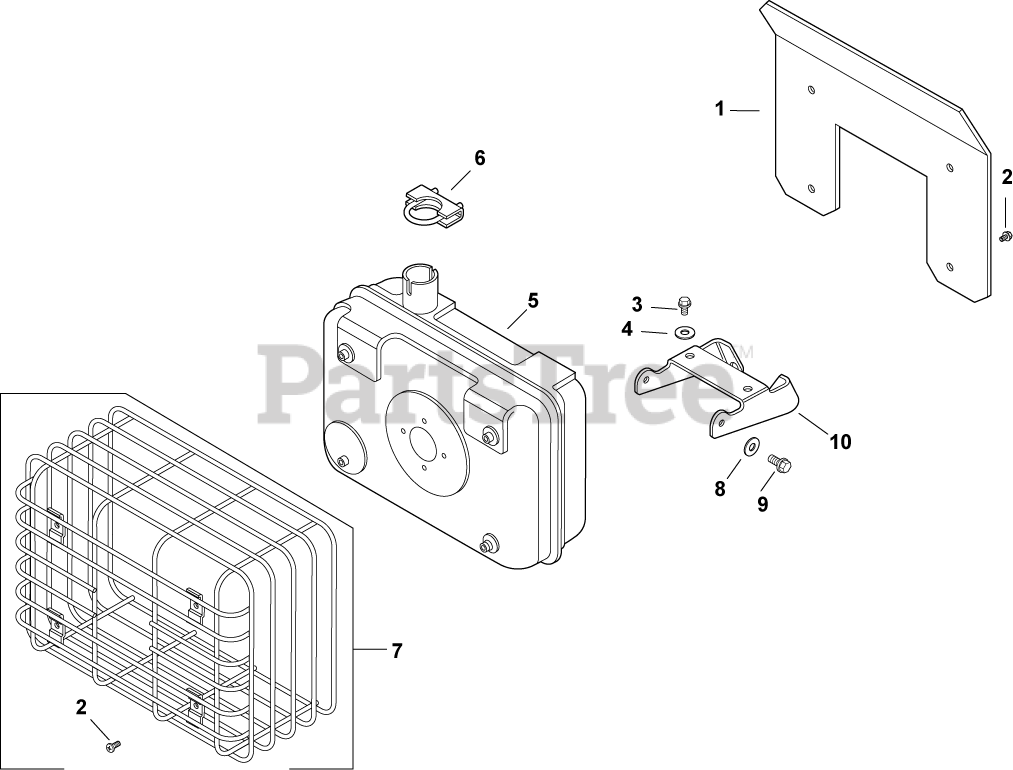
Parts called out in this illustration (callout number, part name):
1	HEAT SHIELD, MUFFLER USE 24 314 58-S
2	SCREW, HVY FLG M5X.8X10
3	SCREW, FLG M8X1.25X25
4	WASHER, FLAT
5	MUFFLER, STARTER SIDE/STRAIGHT USE 24 068 156-S
6	CLAMP, MUFFLER
7	KIT, WIRE GUARD
8	WASHER, SPRING LOCK 1/4"
9	SCREW,FLG THD FRM M6X1.0X16-(#25086397S)
10	BRACKET, MUFFLER
